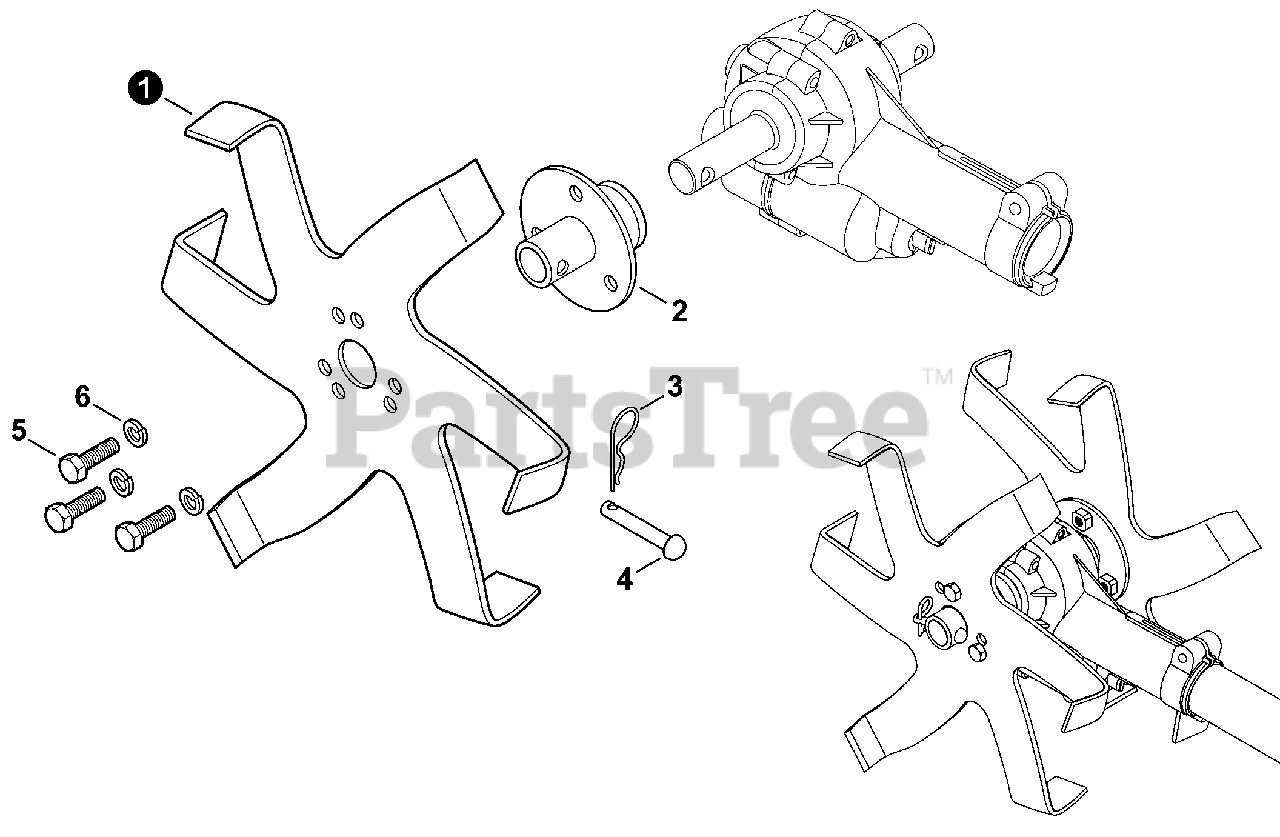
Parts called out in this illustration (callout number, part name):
2	HUB, TINE
3	PIN, COTTER 5
4	PIN, CLEVIS
5	BOLT 6×10
6	WASHER, SPRING 6
